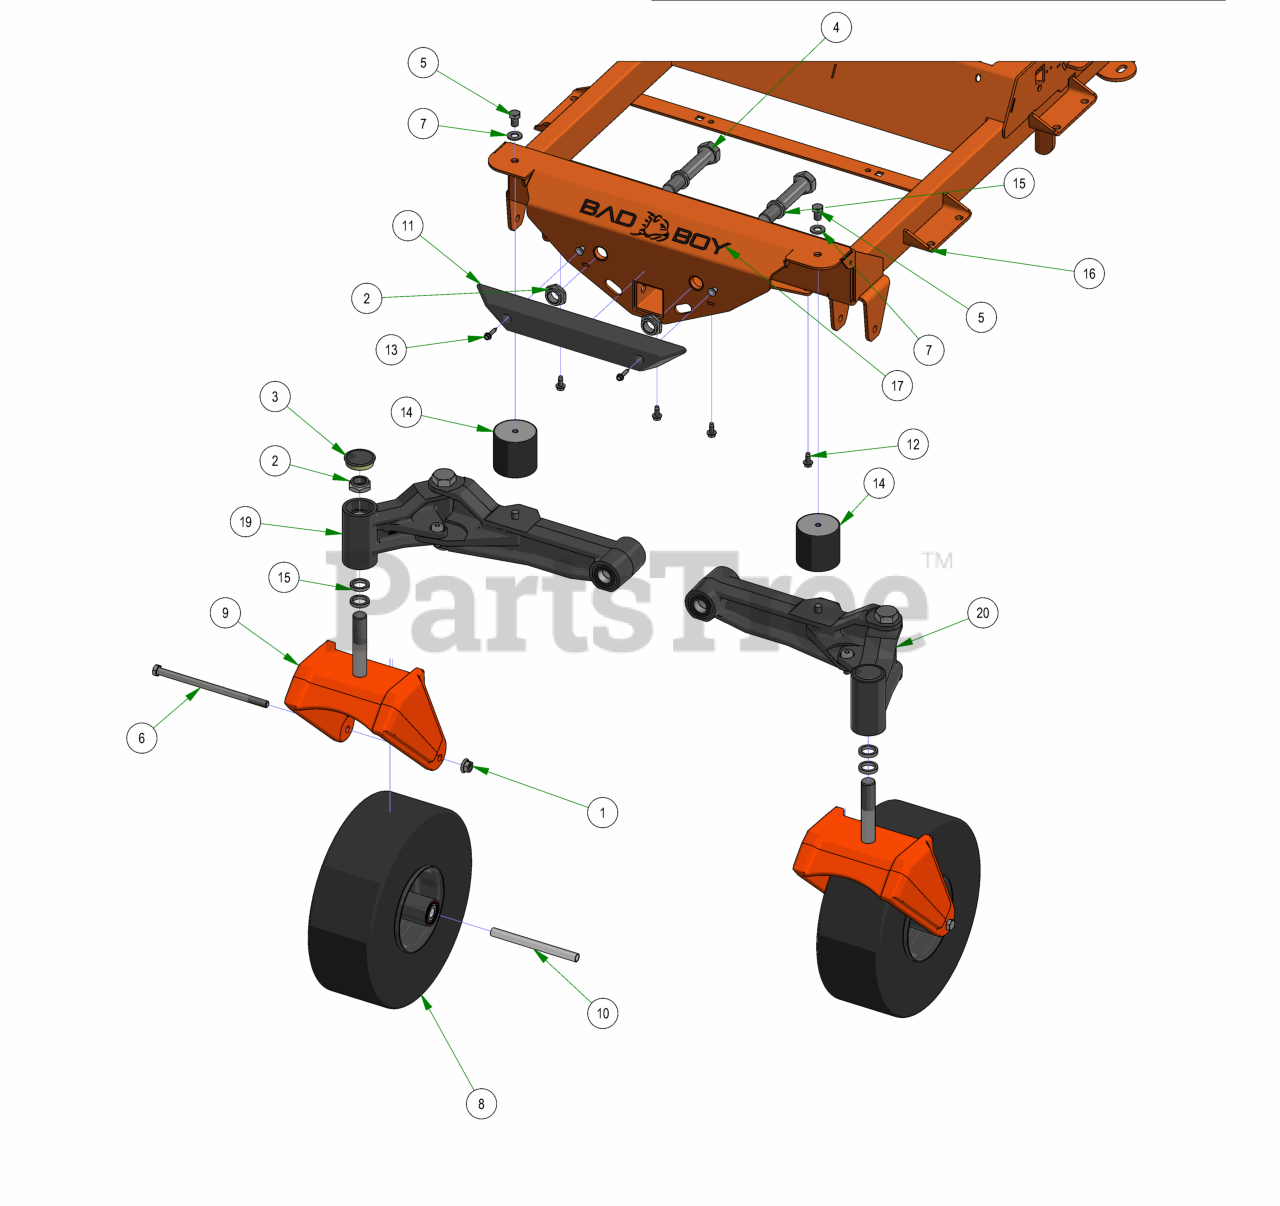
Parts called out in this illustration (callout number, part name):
1	1/2-13 NYLON INSERT FLANGE LOCKNUT ZINC
2	1"-14 NYLON INSERT JAM LOCKNUT ZINC
3	2017 Bearing Cover
4	1"-14 X 5-1/2 HEX CAP SCREW (GR.8) ZINC YELLOW
5	1/2-13 X 3/4 HEX CAP SCREW (GR.5) ZINC
6	1/2-13 X 9 HEX CAP SCREW (GR.5) ZINC
7	1/2 SAE FLAT WASHER (1-1/16" OD) GR.8 ZINC YELLOW
8	2019 15x6.00-6 Non Pneumatic Black Front Assembly
9	2020 R Series Cast Front Fork
10	Front Wheel Spanner
11	2017 XP BUMPER
12	5/16-18 X 3/4 HEX WASHER SLOT (F) TCS ZINC
13	1/4-14 X 1-1/4 HEX WASHER UNSLOT TEK/3 ZINC
14	Vibration Mount-Blue Dot
15	1.02 ID X 1.38 OD X .250 THK SPACER ZINC
16	2022 Horizontal Diesel Frame
17	Flying Bulldog Front Bumper Decal
18	Independetly Articulating Front Suspension Arms Patent Decal
19	2022 61/72 Rogue/Renegade Front Suspension Asy RH
20	2022 61/72 Rogue/Renegade Front Suspension Asy LH
